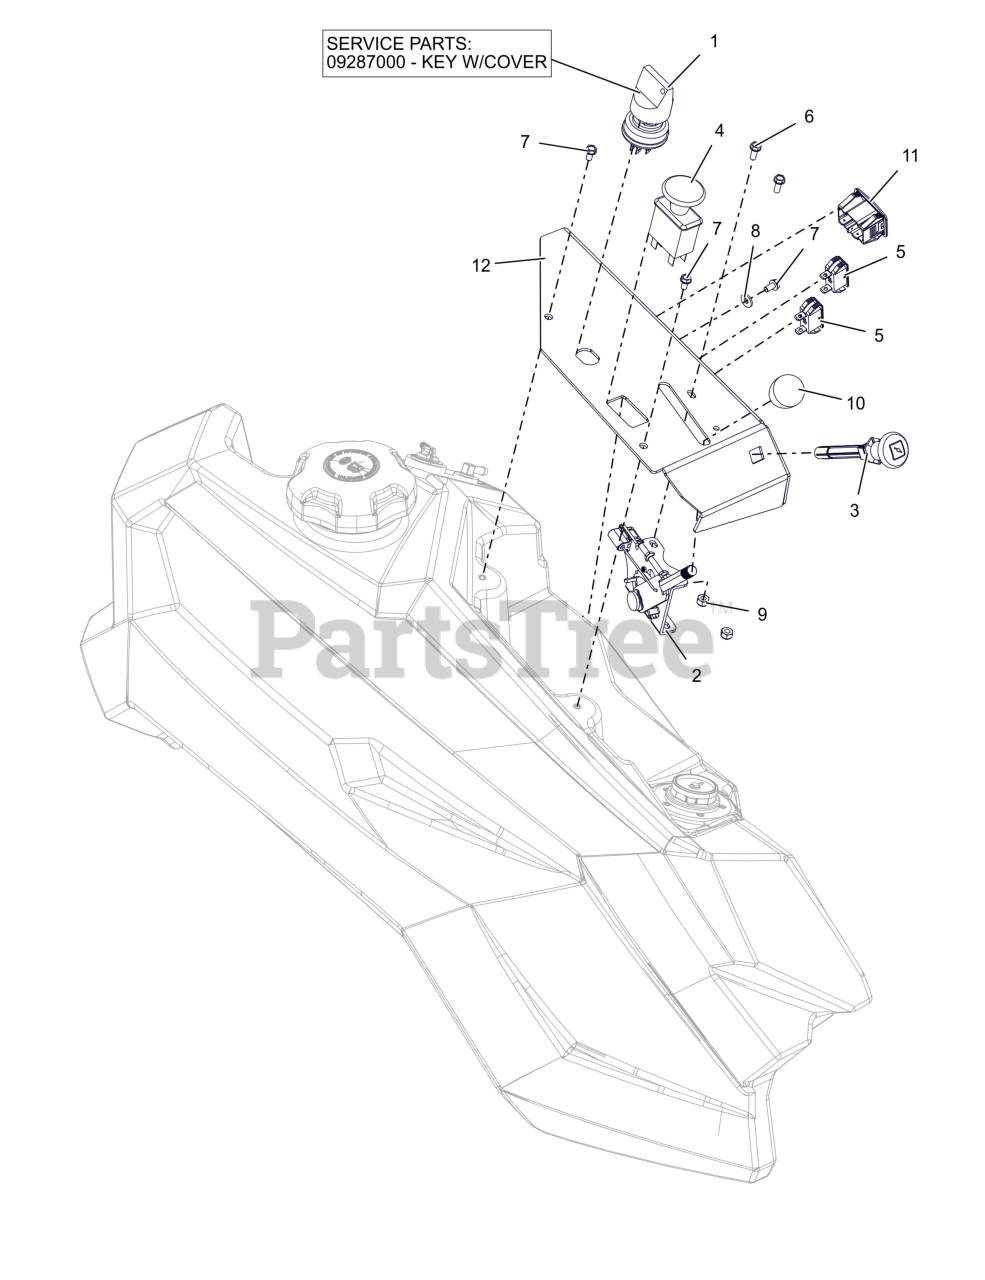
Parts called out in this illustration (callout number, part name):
1	SWITCH, IGNITION
1	KEY, W/ SHIELD
2	CABLE, PRO-CTRL 46.00"
3	CABLE, CHOKE (SNAP IN)
4	SWITCH, CLUTCH
5	LIGHT, INDICATOR (RED)
6	BLT, HWH #10-24X.50 ZCC
7	SCR-MCH 10-24X.38 HWHSTAINLESS
8	WSHR-FL-STL .196X.50X.06 ZC120
9	NUT-LK-NYL #10-24 G2 ZCC
10	KNOB-CONTROL-BLACK .38-16X.50
11	HOUR METER
12	PANEL- RH CONTROL (RED)
